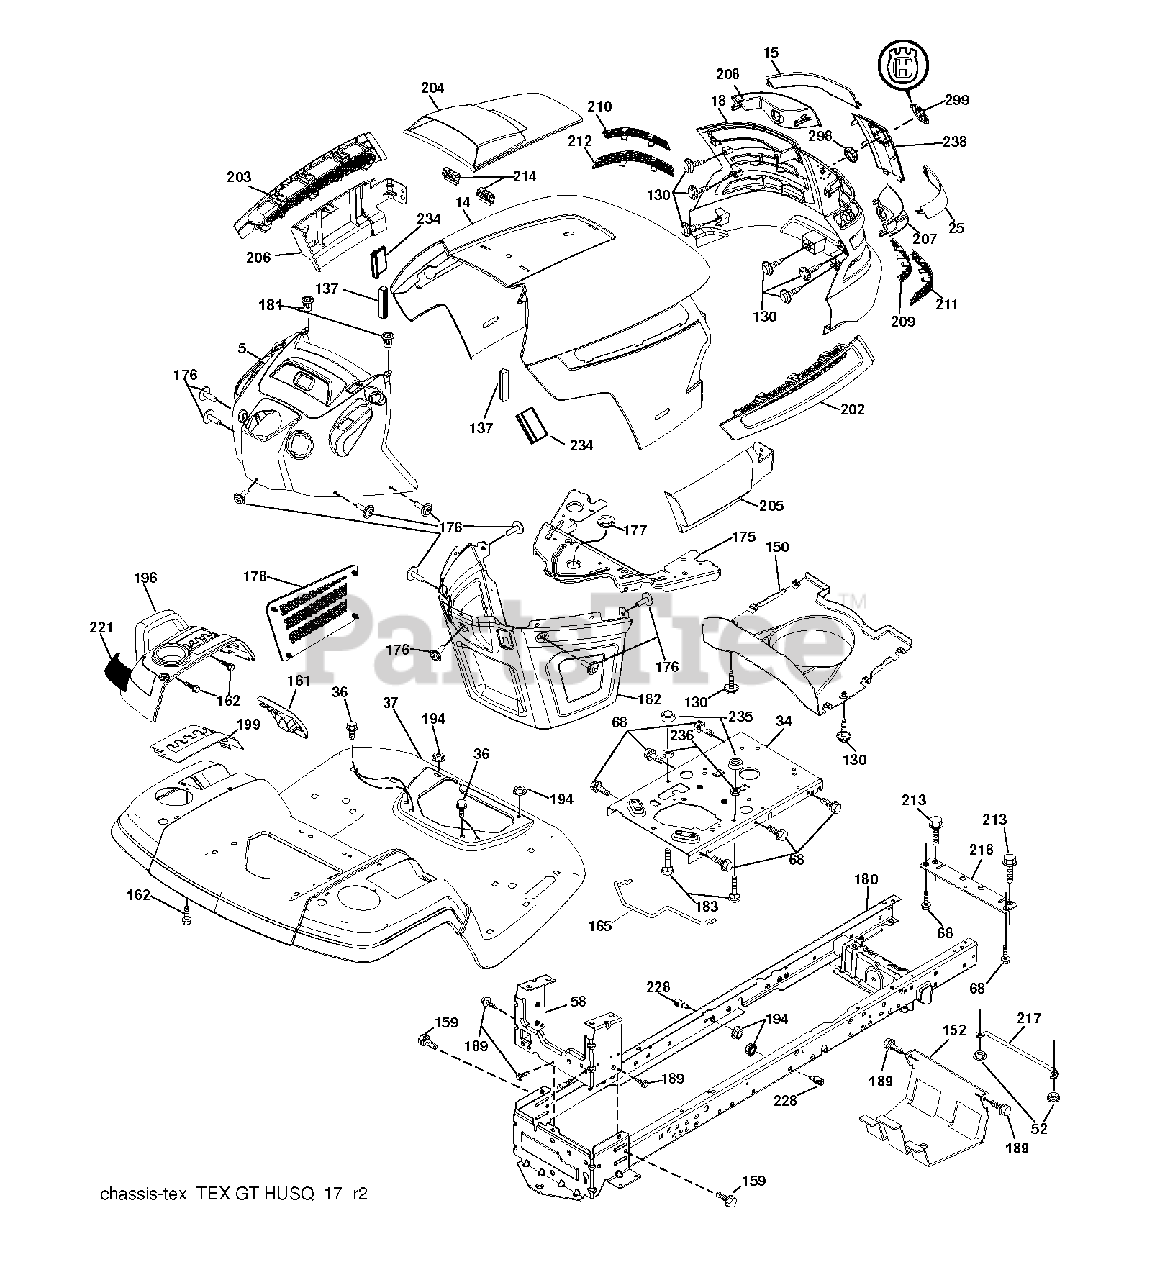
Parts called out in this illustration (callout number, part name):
5	DASH.HUSQ.UPR.ELE.SVMD
14	HOOD.ASM.HUSQVARNA.GT.TEX.ORAN
15	LENS.LH.TEX.GT.HUSQ.CL
18	GRILL.ASM.HUSQ.TG/CRD.W/TRIM
25	LENS.RH.TEX.GT.HUSQ.CL
34	PLATE.ENGINE.WELDED.CHASSIS
36	SCREW 5/16"
37	FENDER.PNT.TX.GT.CH/FW/DL.HUSQ
52	LOCKNUT
58	DRAWBAR.UPPER.2PC,LRG.FENDER
68	SCREW LT
130	SCREW.#10 X 0.750.BOS
137	BUMPER DASH
150	AIR.DUCT.HOOD.TEX.GT.HUSQ
152	SHIELD.BROWNING.W/TEX
159	SCREW, 3/8-16X3/4
161	CONSOLE.WINDOW.FUEL.HUSQ.GT
162	SCREW.HI-LO.CONSOLE
165	SUPPORT.TANK.REAR.W/TEX
175	PLATE.CROSSMEMBER.HUSQ
176	SCREW.#10-24X5/8.RN.QU
177	BUSHING, STEERING
178	CARGO.ASM.NET.TXGT.W/C
180	CHASS.WLDMNT.TLT.12GA/2PC.20"
181	BUSHING.MNT.FEND.CRGO.TEX.49
182	DASH.LOWER.COMMON.12V.ADAPTOR
183	BOLT.5/16-18X1-1/4 FULL THD
189	SCREW
194	NUT LOCK HEX FLANGE 5/16-18
196	SUBASM.CONSOLE.HUSQ.GT.DECKLFT
199	PLATE.DECK.LIFT.HUSQVARNA.GT
202	VENT.SIDE.HOOD.RH.HUSQ
203	VENT,SIDE.HOOD.LH.HUSQ
204	VENT.TOP.HOOD.HUSQVARN
205	HOOD SIDE SKIRT RH
206	SKIRT.HOOD.SIDE.HUSQ.L
207	BEZEL.RH.TEX.GT.HUSQ
208	BEZEL.LH.TEX.GT.HUSQ
209	INSERT.HEX.GRILL.HUSQ.GREY
210	INSERT.HEX.GRILL.HUSQ.
211	INSERT.HEX.GRILL.HUSQ.
212	INSERT.HEX.GRILL.HUSQ.
213	BOLT
214	CLIP.RETAINER.TINNER.
217	ROD.PIVOT.HOOD
218	X-PIECE.HOOD.STOP.NON/
221	REFLECTOR.LH.TEX GT HU
228	STUD.FASTNER.W/ANTI-ROTATE
234	BUMPER.HOOD.TEX.HUSQVARNA
235	SPACER FENDER
236	NUT.CENTERLOCK.5/16-
238	TRIM.HUSQ.TG/CRD.SERVICE
298	NUT PUSH M
299	RP LOGO
